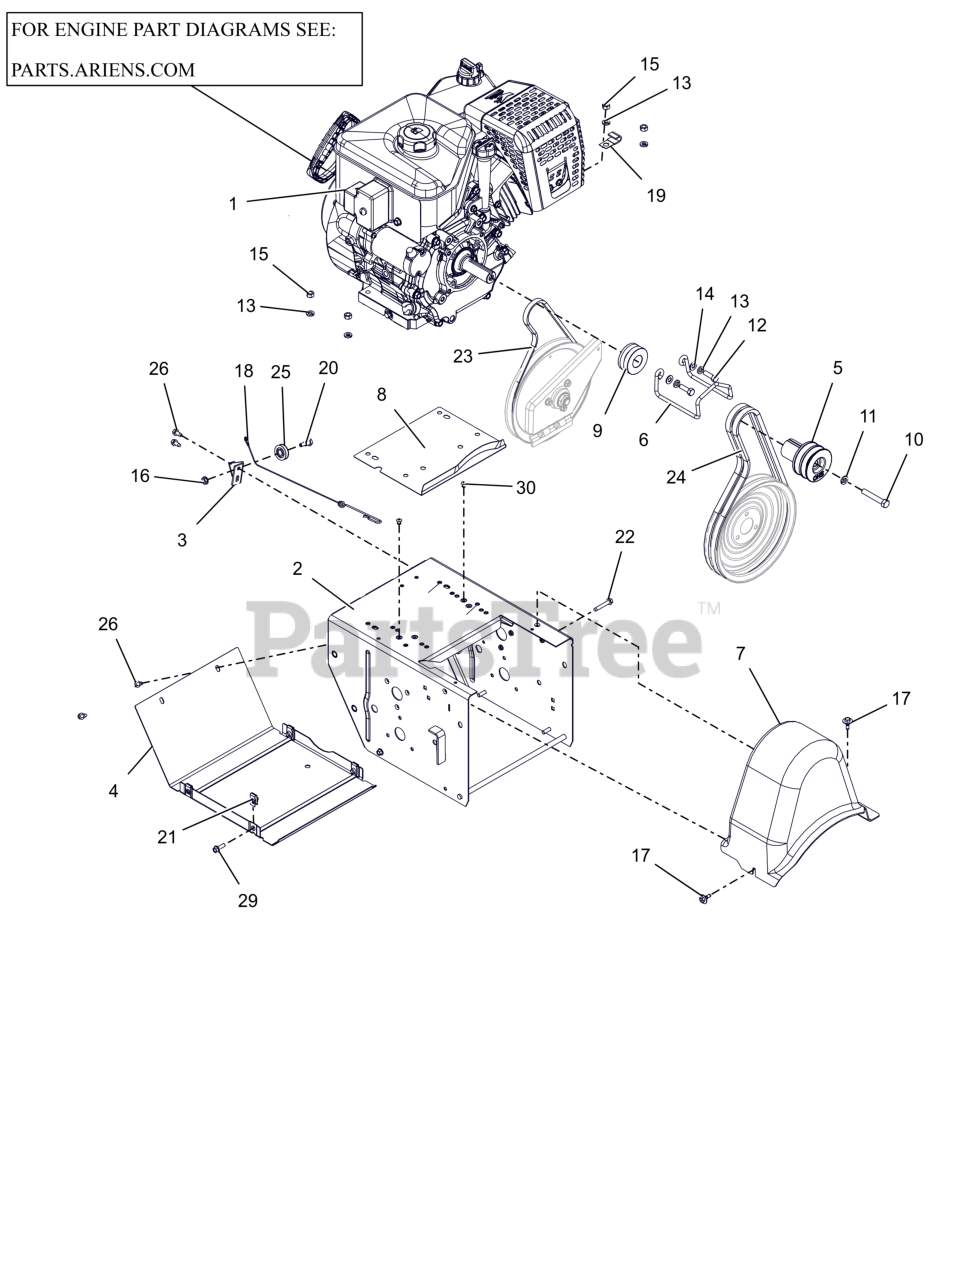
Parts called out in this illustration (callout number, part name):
1	ENGINE, AX369 GEN3 120V/60W
2	FRAME, MAIN - 14GA DELUXE (ORANGE)
3	BRACKET, CABLE PULLEY
4	COVER, BOTTOM
5	SHEAVE,ATTACHMENT-SHO 2 GRV
6	FINGER, BELT
7	COVER, BELT-LARGE
8	BAFFLE, WATER - LARGE BLOCK
9	SHEAVE, TRACTION (KEYLESS)
10	BLT, HEX .38-24X2.25 G5 ZCC
11	WSHR,LK-REG .375X.094 ZCC
12	BLT, HEX 0.3125-24X1 G5 ZCC
13	WSHR, LK-HVY .312X.097 ZCC
14	WSHR,FLT .344X.688X.065 ZCC
15	NUT, HEX .312-18 ZCC
16	NUT-LK-TOP-FLG .250-20 GF ZCC
17	SCR-TAP .25-20X.5 CAPTIVE
18	CABLE, LOWER TRACTION,SS & PRO
19	J-CLAMP
20	BOLT, SHLDR -.375 X .375 X .25-20
21	NUT-RTNR .25-20X.56
22	SCR,TAP .25-20X1.50 HWH TR ZCC
23	V-BELT, 3L-WRAPPED
24	V-BELT, HA-RAW EDGE (SET)
25	PULLEY, CABLE
26	SCR-TAP .25-20X.50 HWH ZCC
29	BLT, HWH .25-20X.75 G5 ZCC
30	RVT, POP .1875 ZCC
